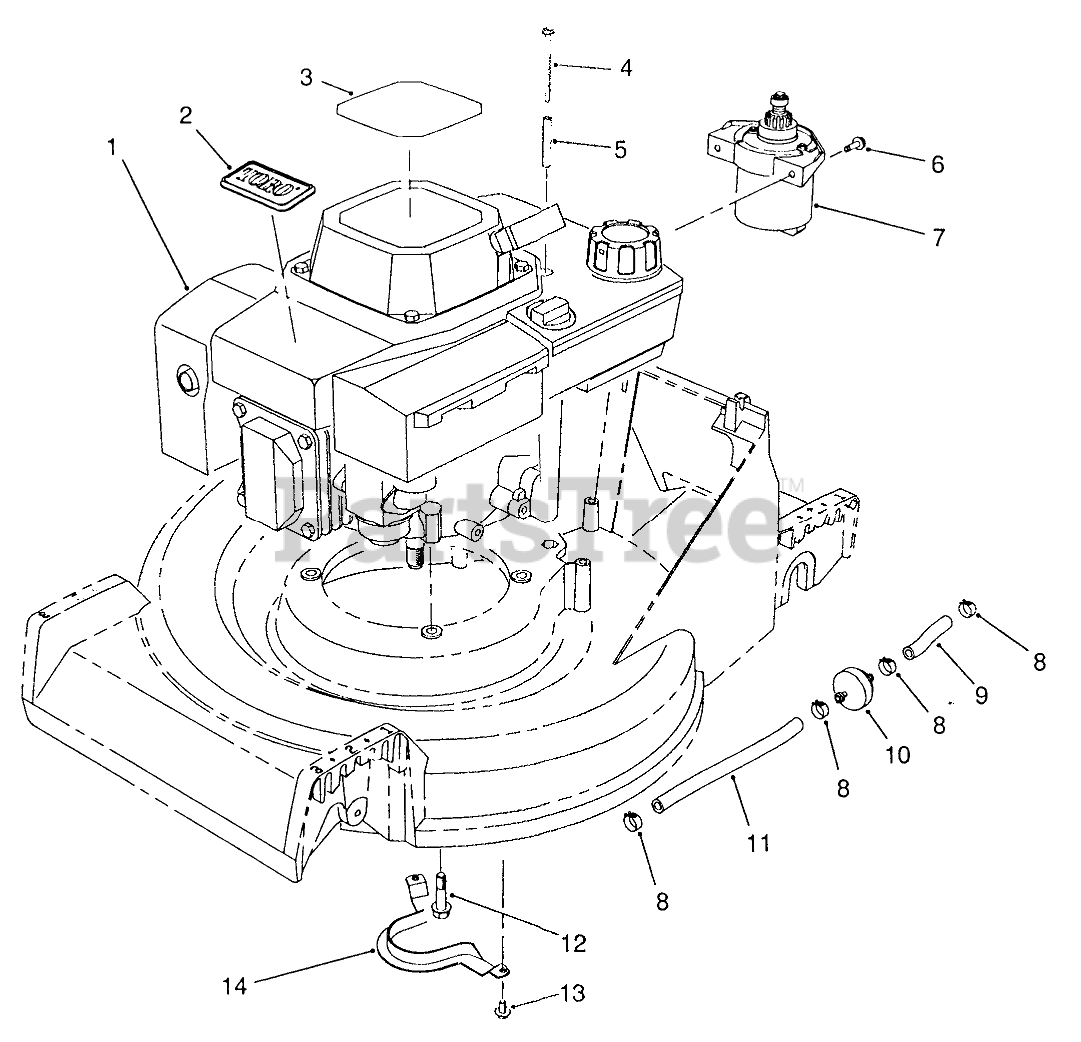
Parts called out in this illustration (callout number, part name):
1	ENGINE ASSY OHV BBC/K
2	TORO LOGO PLT
3	DECAL-HV INT'L
4	THRD FORMING SCREW
5	TUBULAR SPACER
6	SCREW
7	STARTER MOTOR ASM
8	CLAMP-FUEL LINE
9	LINE-GAS
10	FILTER-FUEL
11	HOSE-FUEL
12	SCREW-HWHTF
13	SCREW-HWHTF
14	Guide-Belt
